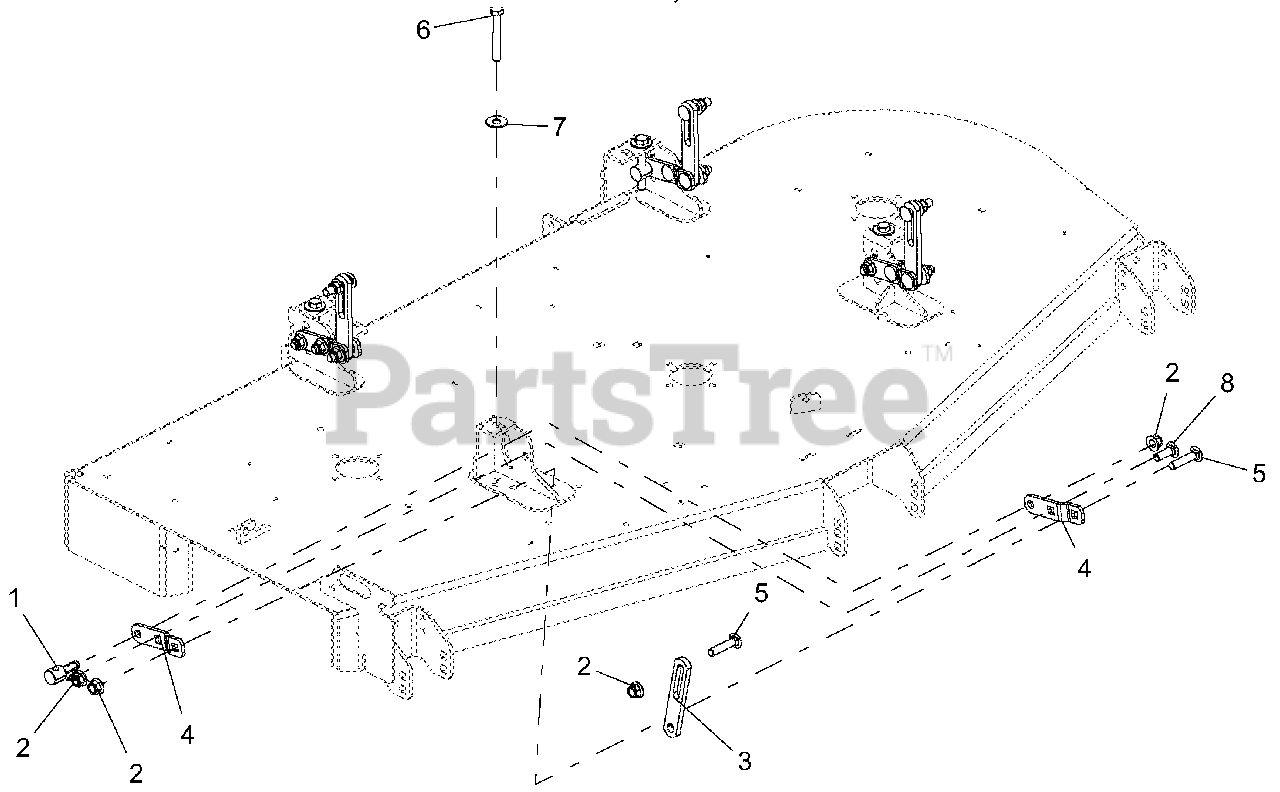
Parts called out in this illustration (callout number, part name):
1	TRUNNION, .50-13
2	NUT-LK-NYL-FLG .50-13 YWZC
3	LINK, DECK LIFT - LONG
4	BRKT, DECK LEVELING-BLACK
5	BLT-RDHDSQNK .50-13X2.25YG5
6	BLT-HEX .50-13X3.50 GR5 YFTHWZC
7	WSHR-FL-STL.563X1.38X.109YWZC
8	BLT-RDHDSQNK .50-13X1.50 G5 YWZC
